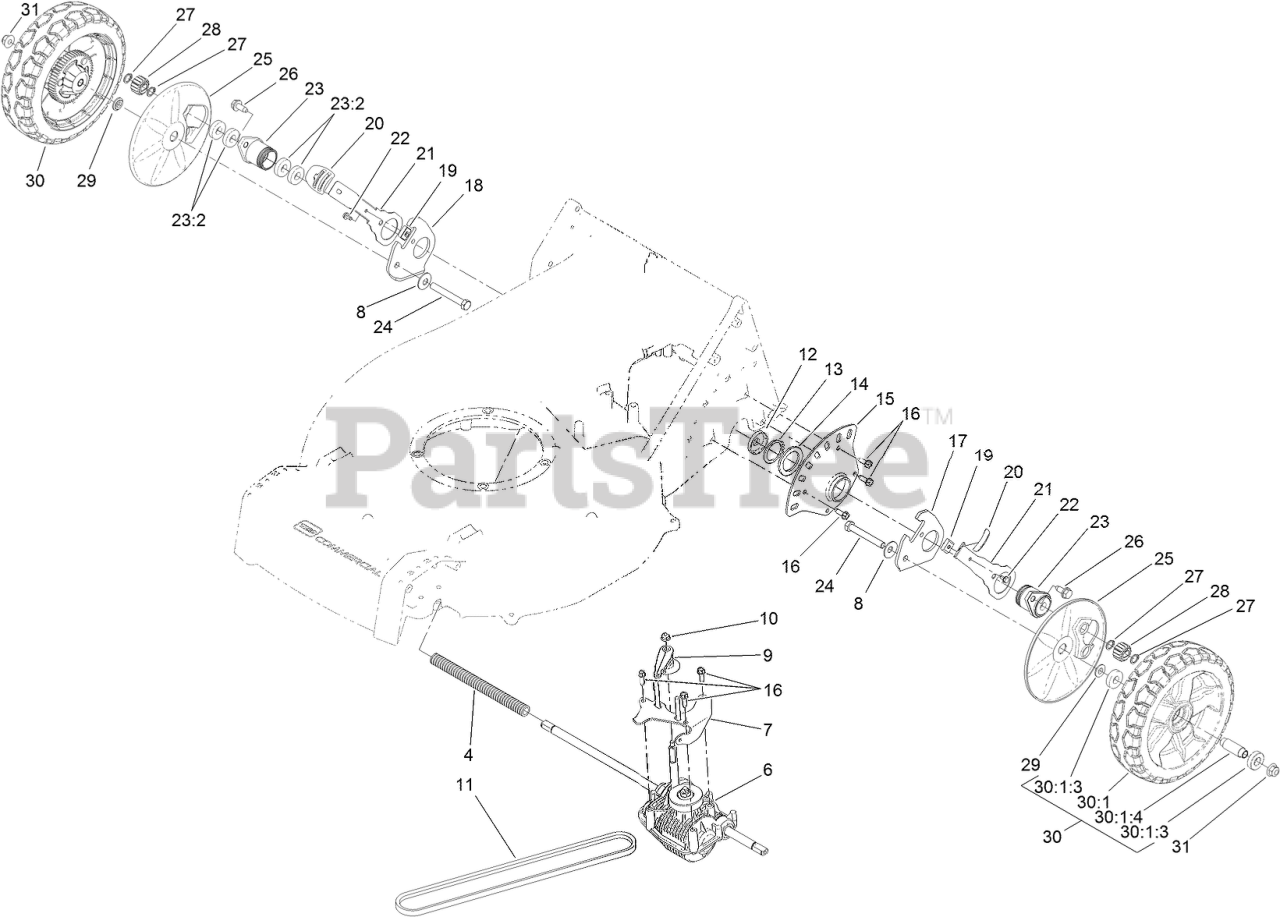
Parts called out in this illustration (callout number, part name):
4	Cover-Shaft, Drive
6	TRANSMISSION
7	GUIDE-BELT
8	WASHER-SPRING
9	LEVER-SHIFT
10	NUT-HF
11	BELT-V
12	COVER-BEARING
13	RING-RETAINING
14	Washer-Thrust
15	PLATE-HOC, REAR
16	SCREW-HWHTF
17	ARM-PIVOT, REAR LH
18	ARM-PIVOT, REAR RH
19	KEY-ARM, SPRING
20	KNOB-LEVER, HOC
21	ARM-SPRING, REAR
22	SCREW-HWH
23	RETAINER ASM
23:2	BEARING-WHEEL
24	SCREW-HH
25	COVER-WHEEL
26	SCREW-HWHTF
27	RING-RETAINING
28	GEAR-PINION, 15T
29	SPACER-COVER, WHEEL
30	WHEEL ASM
30:1	WHEEL
30:1:3	BEARING-WHEEL
30:1:4	SPACER
31	NUT-HF, NI
